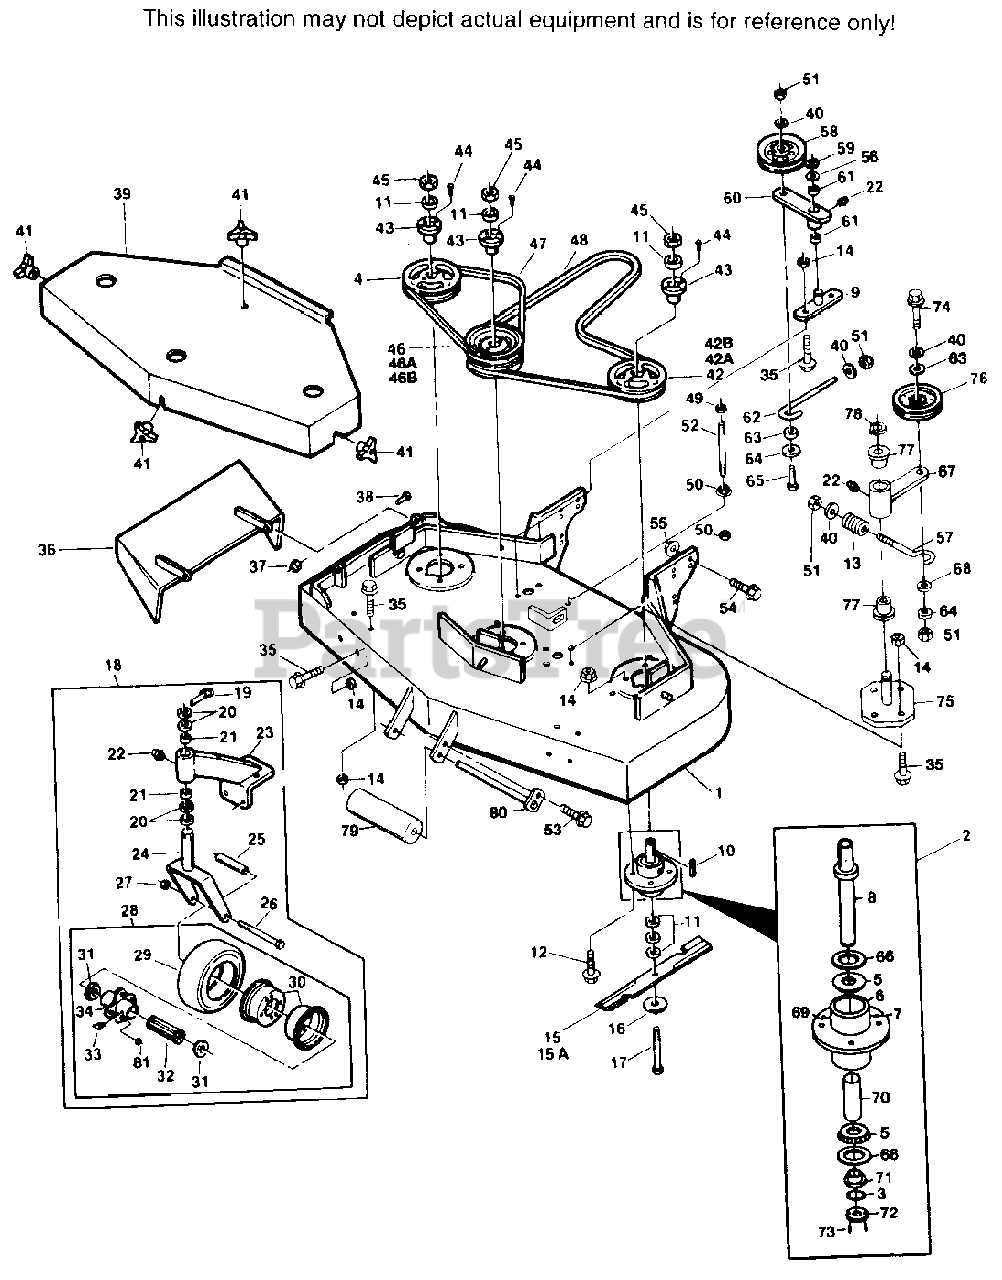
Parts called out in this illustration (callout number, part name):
2	SPINDLE ASSEMBLY
3	RETAINING RING, 1" EXTERNAL INVERTED
4	PULLEY
5	TAPERED BEARING
6	SPINDLE HOUSING
7	GREASE FITTING STR. 5/16 SERRATED
8	SPINDLE SHAFT, TAPERED BEARING
9	IDLER PIVOT
10	KEY, 1/4 X 1/4 X 2"
11	SPACER, CUTTER BLADE - SMALL
12	CAPSCREW 5/16-18 X 1-1/4"
13	SPRING, CUTTER DECK
14	SERRATED FLANGE NUT, 5/16-18
16	FLATWASHER, 5/8" W
17	HEX HEAD BOLT, 5/8-11 X 9-1/2"
18	CASTER ASSEMBLY,(INCL. 19-28)
19	QUICK PIN
20	SPACER, CASTER YOKE, 1/2" THICK
21	BRONZE BEARING
22	GREASE FITTING
23	SUPPORT ASSEMBLY,(INCL. 21-23)
24	CASTER YOKE
25	SLEEVE, CASTER WHEEL BEARING
26	HEX HD BOLT, 1/2-13 X 5-1/2"
27	ELASTIC STOP NUT, 1/2-13
28	WHEEL ASSY.(INCL. 29-34, 81)
29	TIRE ONLY, CASTER WHEEL
30	RIM PAIR, CASTER WHEEL
31	BEARING RETAINER, CASTER WHEEL
32	ROLLER BEARING, CASTER WHEEL
33	GREASE FITTING 45 DEG., 1/4-28
34	HUB ASSEMBLY,(INCL. BOLTS)
35	CAPSCREW, 5/16-18 X 3/4"
36A	DISCHARGE CHUTE
37	HEX NUT, 5/16-18 ELASTIC STOP
40	FLAT WASHER, 3/8" SPECIAL
41	WING NUT, 3/8-16
42	PULLEY
43	TAPERED HUB
46	PULLEY, DOUBLE
49	HEX NUT, 3/8-16, CENTERLOCK
50	NUT, 3/8-16, SERRATED FLANGE
51	ELASTIC STOP NUT, 3/8-16
52	SUPPORT, BELT COVER
53	CAPSCREW, 5/16-18 X 1/2" SERRATED FLANGE HEX
54	CAPSCREW, 7/16-14 X 1" SERRATED FLANGE HEX
55	NUT, 7/16-14 SERRATED FLANGE
56	FLAT WASHER 3/4" SPECIAL
56A	FLAT WASHER 3/4" SPECIAL
57	J-HOOK
58	IDLER PULLEY, "V" GROOVE
59	RETAINING RING, 3/4" EXT. "E"
60	IDLER ARM ASSY.(INCL. 22 & 61)
61	BRONZE BEARING
62	J-ROD, IDLER PULLEY
63	SPACER, J-ROD
64	WASHER, 3/8 X 1-1/2 X 16 GA.
66	SEAL
67	IDLER ARM ASSY(INCLUDES 22&77)
68	SPACER, J-ROD
69	RELIEF FITTING, CUTTER SPINDLE
70	SLEEVE, CUTTER SPINDLE
71	SPINDLE BUSHING
72	SPACER, LARGE
75	IDLER PIVOT
76	IDLER PULLEY, BELT CLUTCH
77	BRONZE BEARING
78	RETAINING RING
79	GUIDE ROLLER
80	ROLLER SHAFT
NS	INNER TUBE ONLY, CASTER WHEEL
